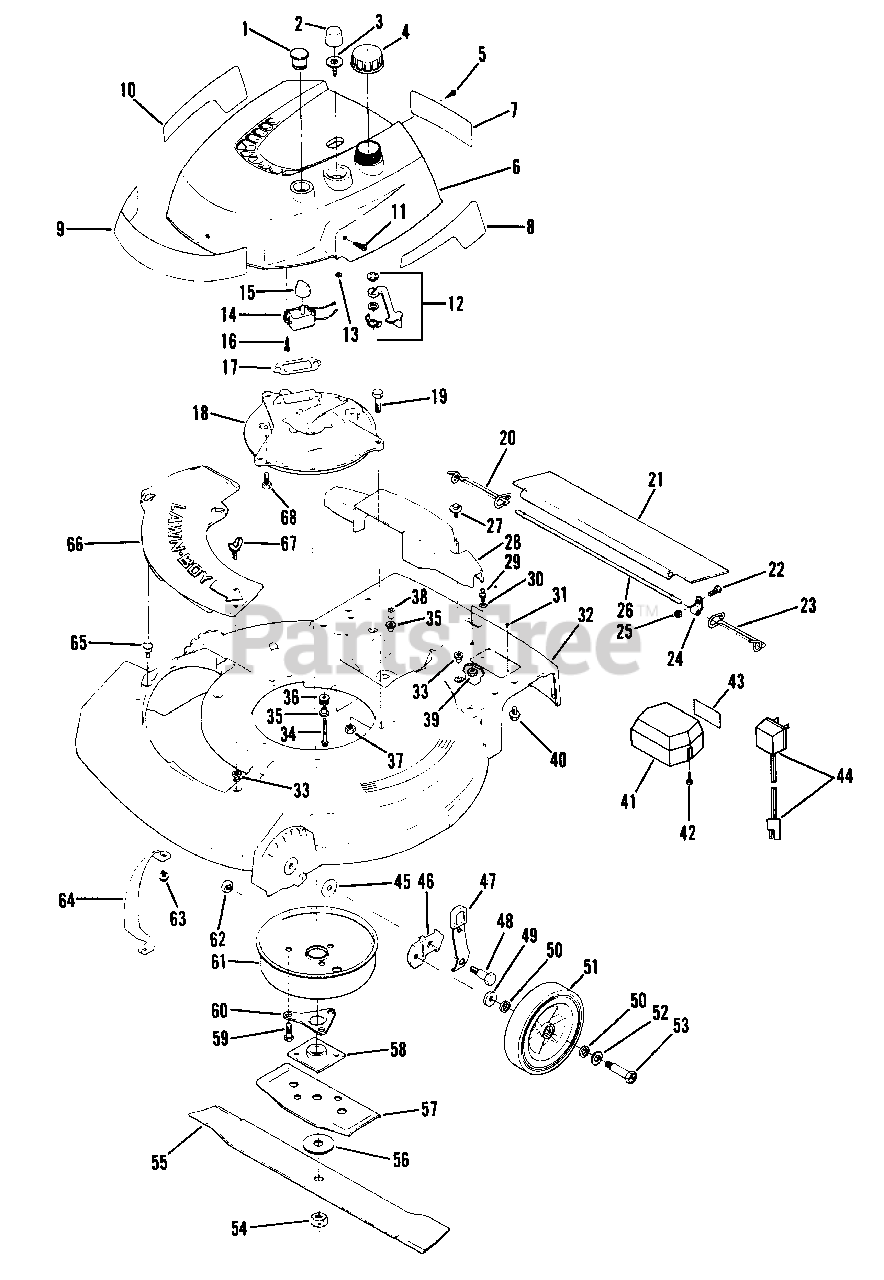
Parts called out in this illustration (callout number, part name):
1	Plug
2	Bulb-Primer
3	Base-Primer
4	Fuel Cap
5	Screw-Shroud to C.D. Bracket
6	Shroud-Engine
7	Decal-Instructions
8	Decal-L.H. 21"
9	Decal-Lawn-Boy
10	Decal-R.H. 21"
11	Screw-Shroud Mounting
12	Fuel Shut-Off Assembly
13	Nut
14	Switch-On-Off
15	Knob
16	Screw
17	Gasket-Exhaust
18	Plate-Muffler
19	Screw-Muffler Plate to Housing
20	Spring-R.H.
21	Shield-Trailing
22	Screw
23	Spring-L.H.
24	Clamp
25	Nut
26	Rod-Trailing Shield
27	Screw-Axle Cover Mounting
28	Cover-Drive Axle
29	Ball Stud-Battery Mounting
30	Washer-Ball Stud
31	Screw-Model Plate Mounting
32	Housing
33	Grommet
34	Screw-Sems
35	Spacer
36	Grommet
37	Nut-Muffler Plate to Housing
38	Spacer
39	Nut-Ball Stud
40	Screw-Handle Bracket to Housing
41	Battery Box & Battery Pack Assembly
42	Screw
43	Decal
44	Charger-Battery
45	Washer
46	Bracket-Wheel Height Adjustment
47	Knob & Spring Assembly
48	Shoulder Bolt
49	Washer
50	Washer-Felt
51	Wheel-Front
52	Washer
53	Bolt-Wheel-Front
54	Nut-Blade
55	Blade-21"
56	Washer-Blade
57	Stiffener-Blade
58	Collar & Plate Assembly
59	Screw
60	Support-Crankshaft
61	Muffler Cover Assembly
62	Nut
63	Screw-Sems
64	Toe Bar
65	Screw-Sems-Plate & Chute Mounting
66	Cover Plate
67	Wing Screw
68	Screw-Muffler Plate to Block
